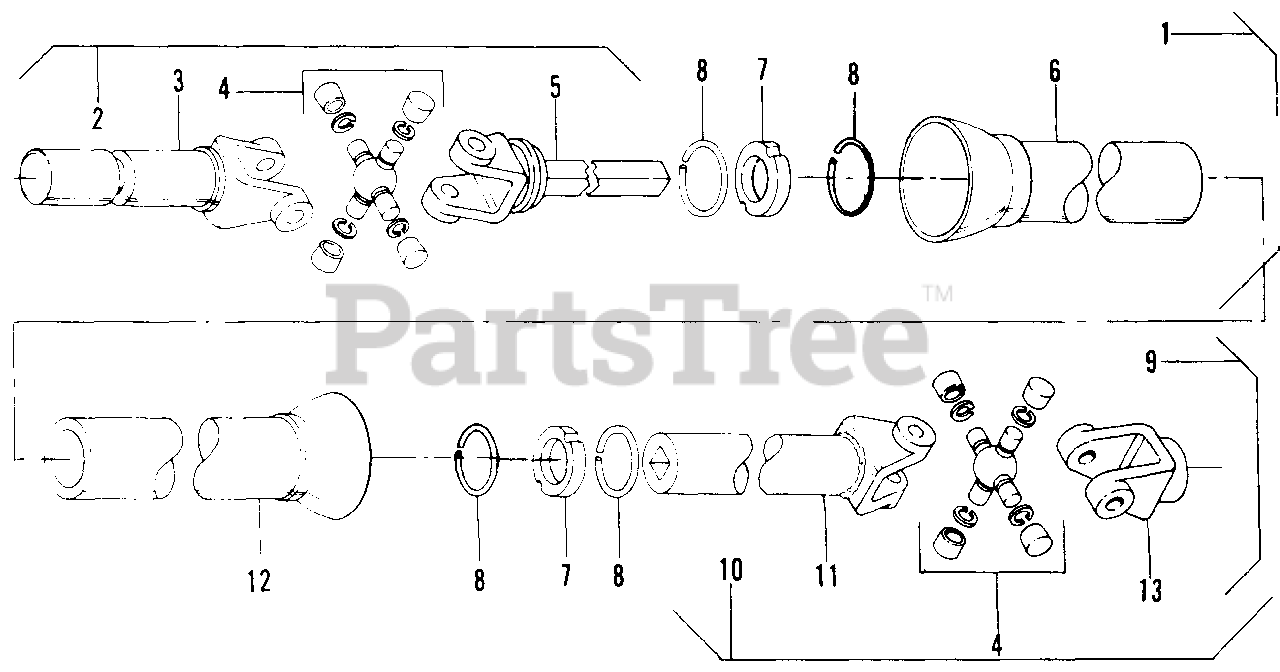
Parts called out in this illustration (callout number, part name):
1	SHAFT, Spline
2	JOINT & SHAFT ASSY, w/Guard
4	KlT, Repair
5	YOKE & SHAFT
6	GUARD ASSY, Female
7	BEARING, Nylon
8	RETAINER, Bearing
9	JOINT & TUBE ASSY
10	JOINT & TUBE
11	YOKE & TUBE
12	GUARD ASSY, Male
